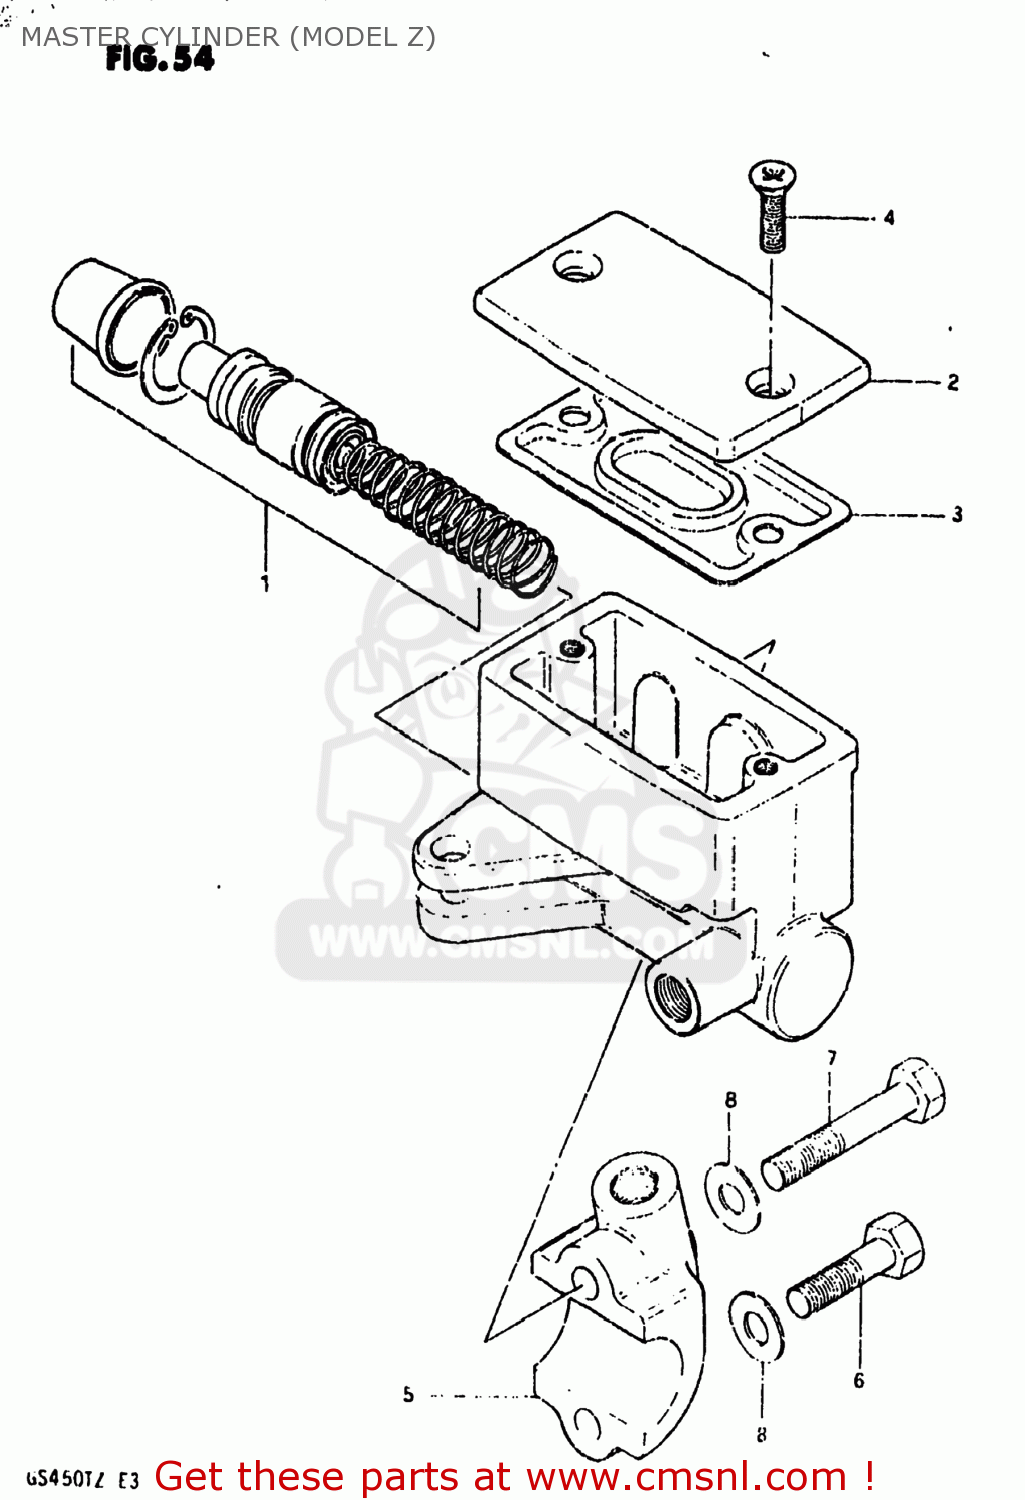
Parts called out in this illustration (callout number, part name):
1	PISTON & CUP SET
2	CAP
3	4
4	SCREW
5	HOLDER
6	BOLT
7	BOLT 6X40
8	LOCK WASHER
